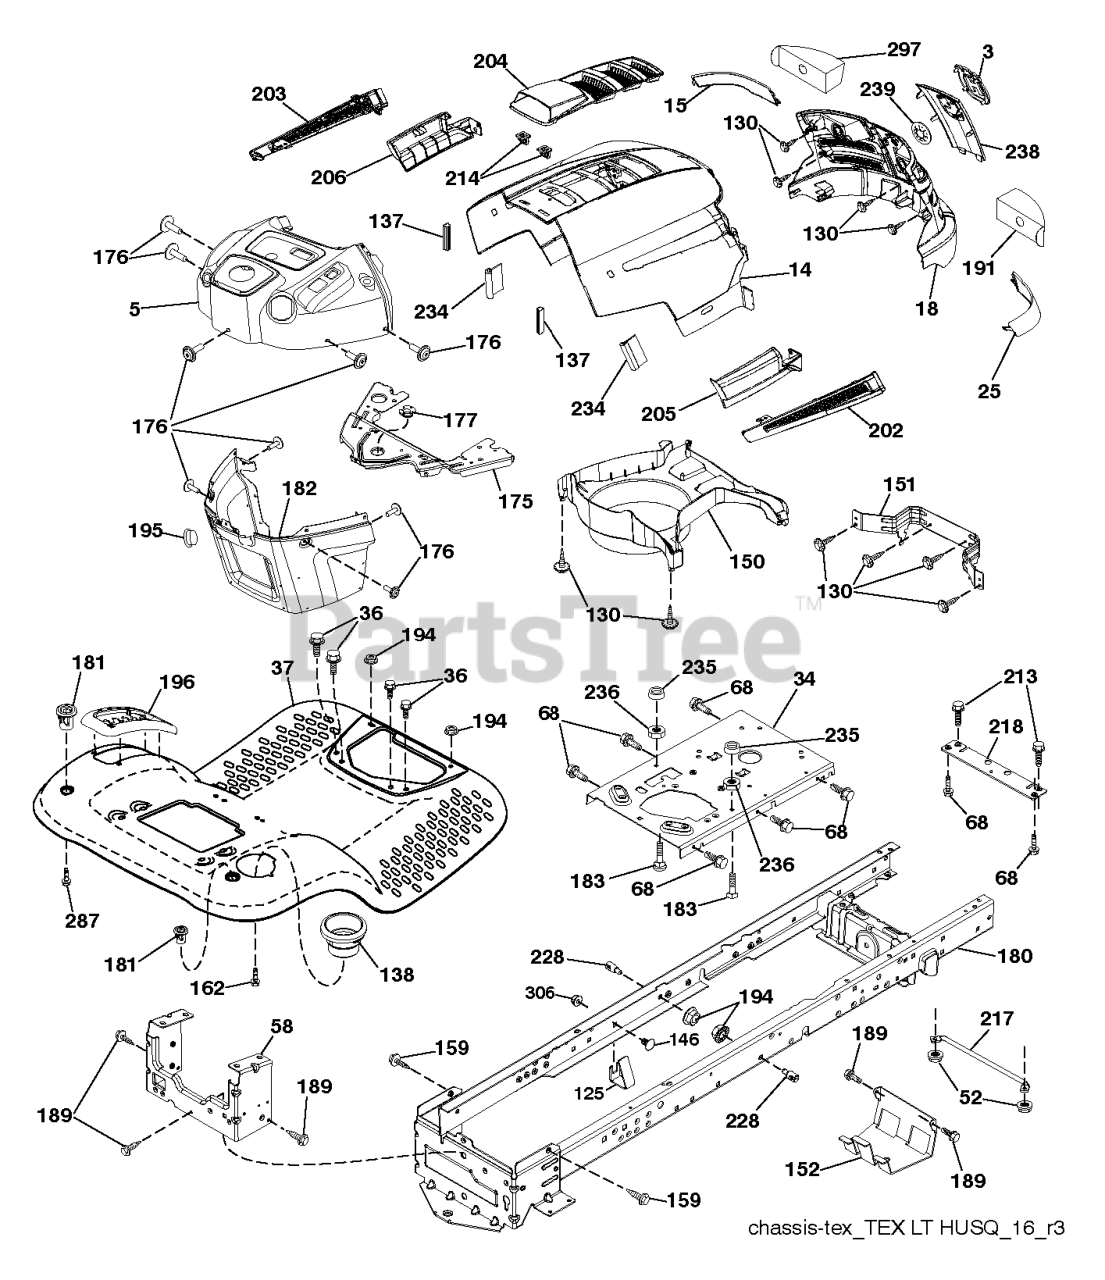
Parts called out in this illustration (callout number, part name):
3	LOGO.HUSQ.GT.LT.CROWN.H
5	SUBASM.DASH.UPPER.W/BUMPER
14	HOOD.HUSQVARNA.LT.ORANGE
15	LENS.HUSQVARNA LT.LH
18	GRILLE.SVC.HUSQVARNA.GREY
25	LENS.HUSQVARNA LT.RH
34	PLATE.ENGINE.WELDED.CHASSIS
36	SCREW 5/16"
37	FENDER.TLT.FS.W/CUPHLD.ORANGE
52	LOCKNUT
58	DRAWBAR UPPER 2PC SMALL FENDER
68	Screw 5/16-18 x 1/2 Hex, Self Tapping 5/16-18 x 1/2
125	CLIP.FUEL.LINE
130	SCREW.#10 X 0.750.BOS
137	BUMPER DASH
138	HOLDER.CUP.LT.GREY
146	BOLT.RDHD.SHT.SQNK.3/8-16X5/8
151	BRACKET PIVOT
152	SHIELD.BROWNING.W/TEX
159	SCREW, 3/8-16X3/4
162	SCREW.HI-LO.CONSOLE
175	CROSSMEMBER
176	SCREW.#10-24X5/8.RN.QU
177	BUSHING STEERING
180	CHASS.WLDMNT.TL.12GA/2P.48/54
181	BUSHING.MNT.FEND.CRGO.TEX.49
182	DASH.LOWER.PREDATOR LT
183	BOLT.5/16-18X1-1/4 FULL THD
189	SCREW
191	INSERT.REFLECTIVE.RH.
194	NUT LOCK HEX FLANGE 5/16-18
195	PLUG.TEX.DASH.SVC.MINDER.GREY
196	DECKLFT.CONSOL FULL ASSM GREY
202	VENT.SIDE.HUSQVARNA.LT.RT
203	VENT.SIDE.HUSQVARNA.LT.LFT
204	SUBASM.TOP.VENT.HUSQ.LT
205	SKIRT.SIDE.HUSQVARNA.LT.RT
206	SKIRT.SIDE.HUSQVARNA.LT.LEFT
213	BOLT
214	CLIP.RETAINER.TINNER.
217	ROD.PIVOT.HOOD
218	X-PIECE.HOOD.STOP.NON/
228	STUD.FASTNER.W/ANTI-ROTATE
234	BUMPER.HOOD.TEX.HUSQVARNA
235	SPACER FENDER
236	NUT.CENTERLOCK.5/16-
238	TRIM.HUSQ LT.668
287	SCREW 1/4X20
297	INSERT REFLECTIVE
306	NUT LOCK FLG 3/8-16 UNC
